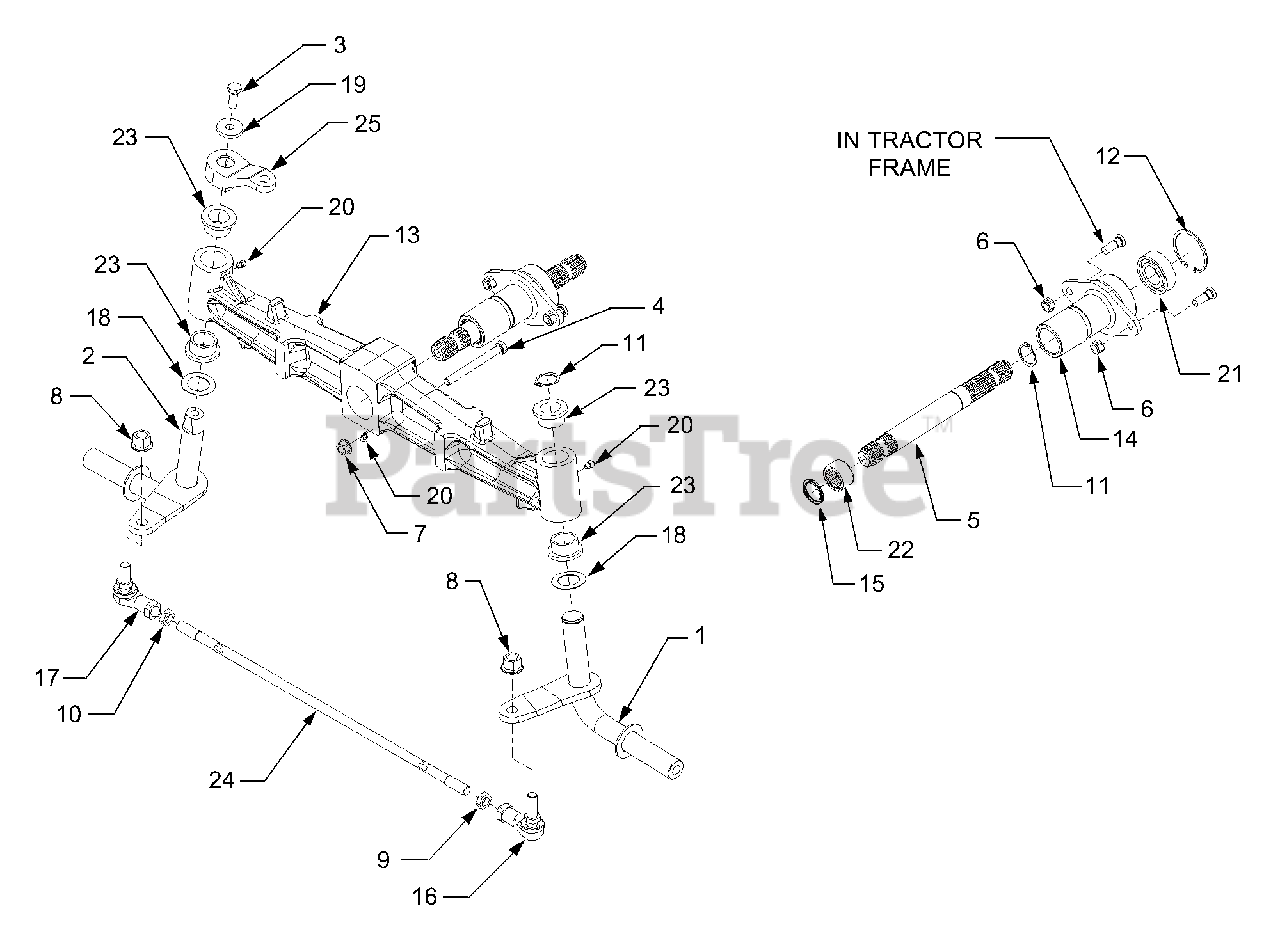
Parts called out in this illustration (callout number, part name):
1	Axle, RH Steering
2	Axle, LH Steering
3	Screw, Hex Cap 3/8-24 x 1.0 GR8
4	Screw, Hex Cap 3/8-16 x 3.5 GR5
5	Shaft, Splined
6	Nut, Hex Center Lock, 3/8-24
7	Nut, Hex Flange Lock, 3/8-16
8	Nut, Hex Flange Lock, M12 x 1.75
9	Nut, Hex - RH, M12 x 1.75
10	Nut, Hex - LH, M12 x 1.75
11	Snap Ring, 1.0 Dia. Shaft
12	Retaining Ring, Internal, 2.0
13	Pivot Axle
14	Axle Carrier
15	Seal, Grease, 1.31 x 1.0
16	Ball Joint, 12MM x 1.75 RH
17	Ball Joint, 12MM x 1.75 LH
18	Washer, Flat, 1.03 x 1.62 x .030
19	Washer, Flat, .406 x 1.25
20	Fitting, Lube, 3/16 Drive
21	Bearing, Ball
22	Bearing, Needle
23	Bearing, Flange
24	Tie Rod, M12 x1.75 RH & LH
25	Steering Arm
